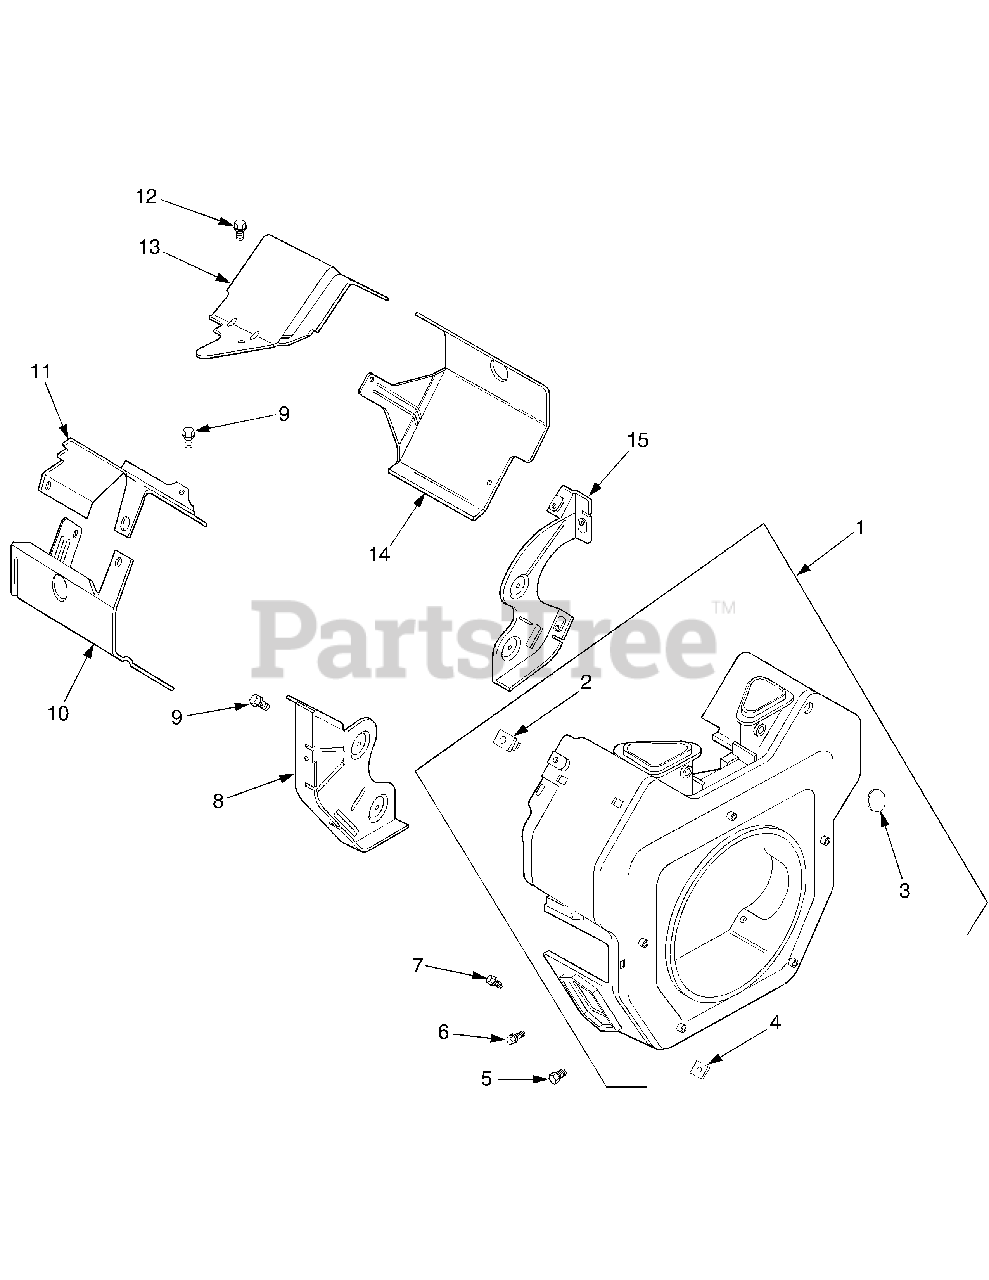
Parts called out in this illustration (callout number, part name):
1	Housing, Blower (Incl. Ref #2-4)
2	Nut, Plastic
3	Plug, Button, 9/16
4	Nut, Plastic
5	Screw, Hex Flange, M5 x 0.8 x 16
6	Screw, Hex Flange, M5 x 0.8 x 16
7	Screw, Hex Flange, M5 x 0.8 x 20
8	Plate, Backing - #2 Side
9	Screw, Hex Flange, M6 x 1.0 x 16
10	Baffle, Cylinder Barrel - #2 Side
11	Baffle, Valley - #2 Side
12	Screw, Hex Flange, M5 x 0.8 x 10
13	Baffle, Valley - #1 Side
14	Baffle, Cylinder Barrel - #1 Side
15	Plate, Backing - #1 Side
